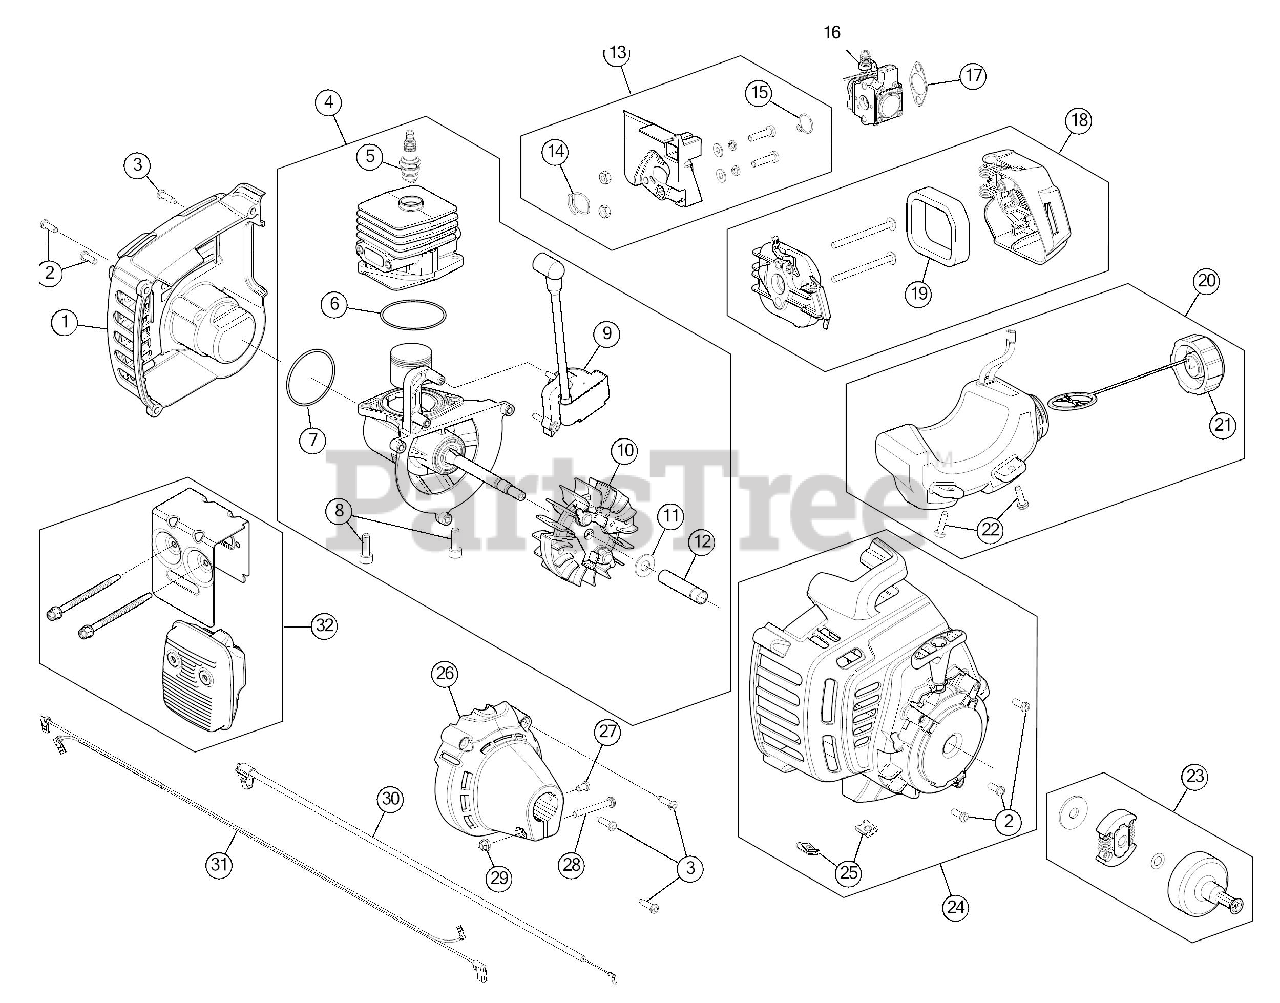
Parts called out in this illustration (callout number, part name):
1	Rear Cover Assembly (incl. 2 & 3)
2	Housing Screw
3	Cover Screw
4	Short Block Assembly
5	Spark Plug
6	Crankcase O-Ring
8	Crankcase Bolt
9	Module Assembly
10	Flywheel Assembly
13	Insulator Assembly (incl. 14 & 15)
14	Insulator O-Ring
15	Carburetor O-Ring
16	Carburetor
17	Air Cleaner Gasket
18	Aircleaner Cover Assembly (incl. 19)
19	Aircleaner Filter
20	Fuel Tank Assembly (incl. 21 & 22)
21	Fuel Tank Cap
22	Fuel Tank Screw
23	Starter Clutch Assembly
24	Starter Housing (incl. 2 & 25)
25	U-shaped Nut
26	Clutch Cover (incl. 3)
27	Anti-rotation Screw
28	Clamp Screw
29	Clamp Nut
30	Throttle Cable
31	Lead Wires
32	Muffler Assembly
